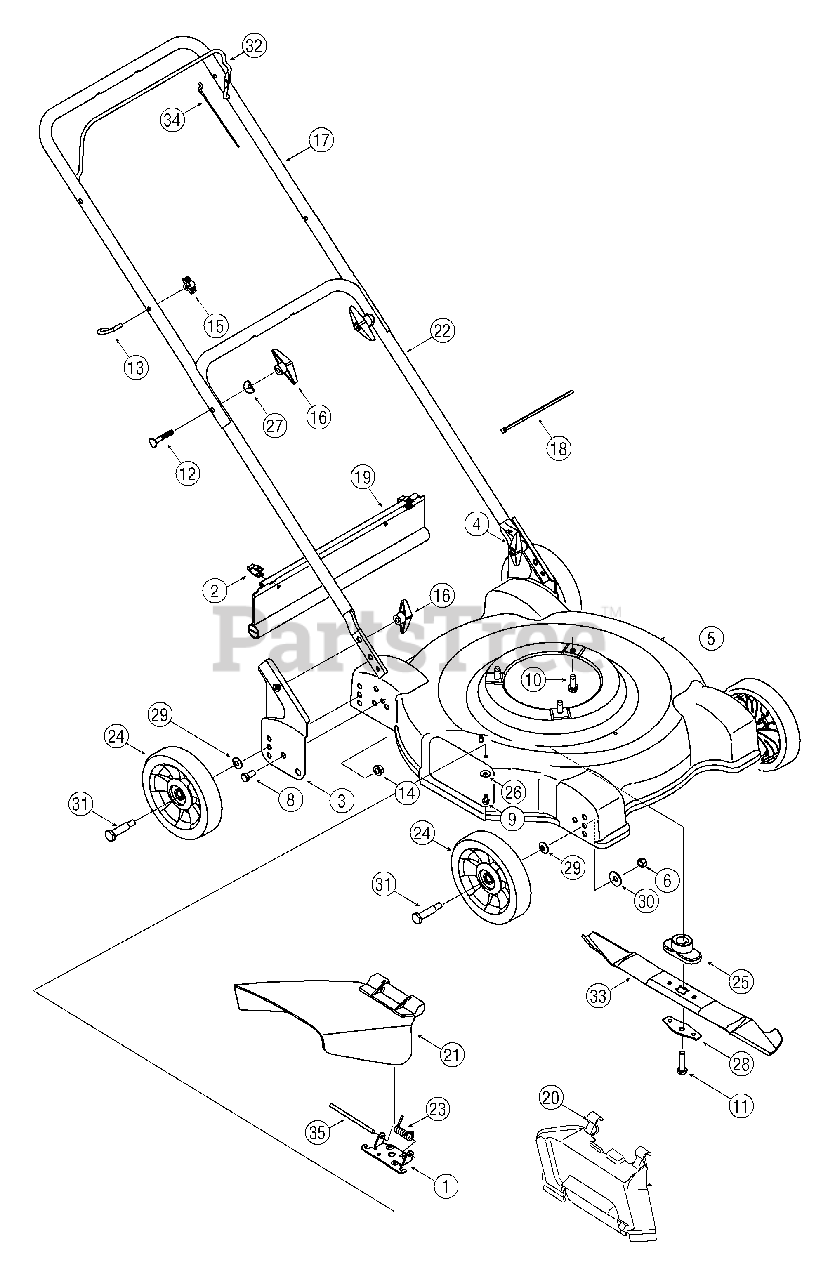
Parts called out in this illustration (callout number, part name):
1	Chute Hinge
2	Hinge Clip
6	Hex Nut, 3/8-16
8	Hex Cap Screw 3/8-16 x .75
9	TT Screw 1/4-20 x 0.5"
10	TT Screw 3/8-16 x 1.0
11	Hex Cap Screw 3/8-24 x 1.5
12	Carriage Bolt 5/16-18 x 2.0
13	Eye Bolt
14	Lock Nut 3/8-16
15	Wing Nut
16	Wing Nut
18	Cable Tie
19	Trail Shield
20	Mulching Baffle
21	Hinged Chute Deflector Assembly
23	Torsion Spring
24	Wheel, 7 x 1.5, Star-Diam Gray
25	Blade Adapter
26	Bell Washer .265 ID x .75 OD
27	Saddle Washer .320 ID x .93 OD
28	Blade Bell Support
29	Bell Washer, .375 x .870 x .063
30	Bell Washer, .390 x 1.13 x .062
31	Shoulder Screw, .498 x 1.635
33	Standard Blade, 22"
34	Blade Control Cable - 37.25"
35	Hinge Pin
